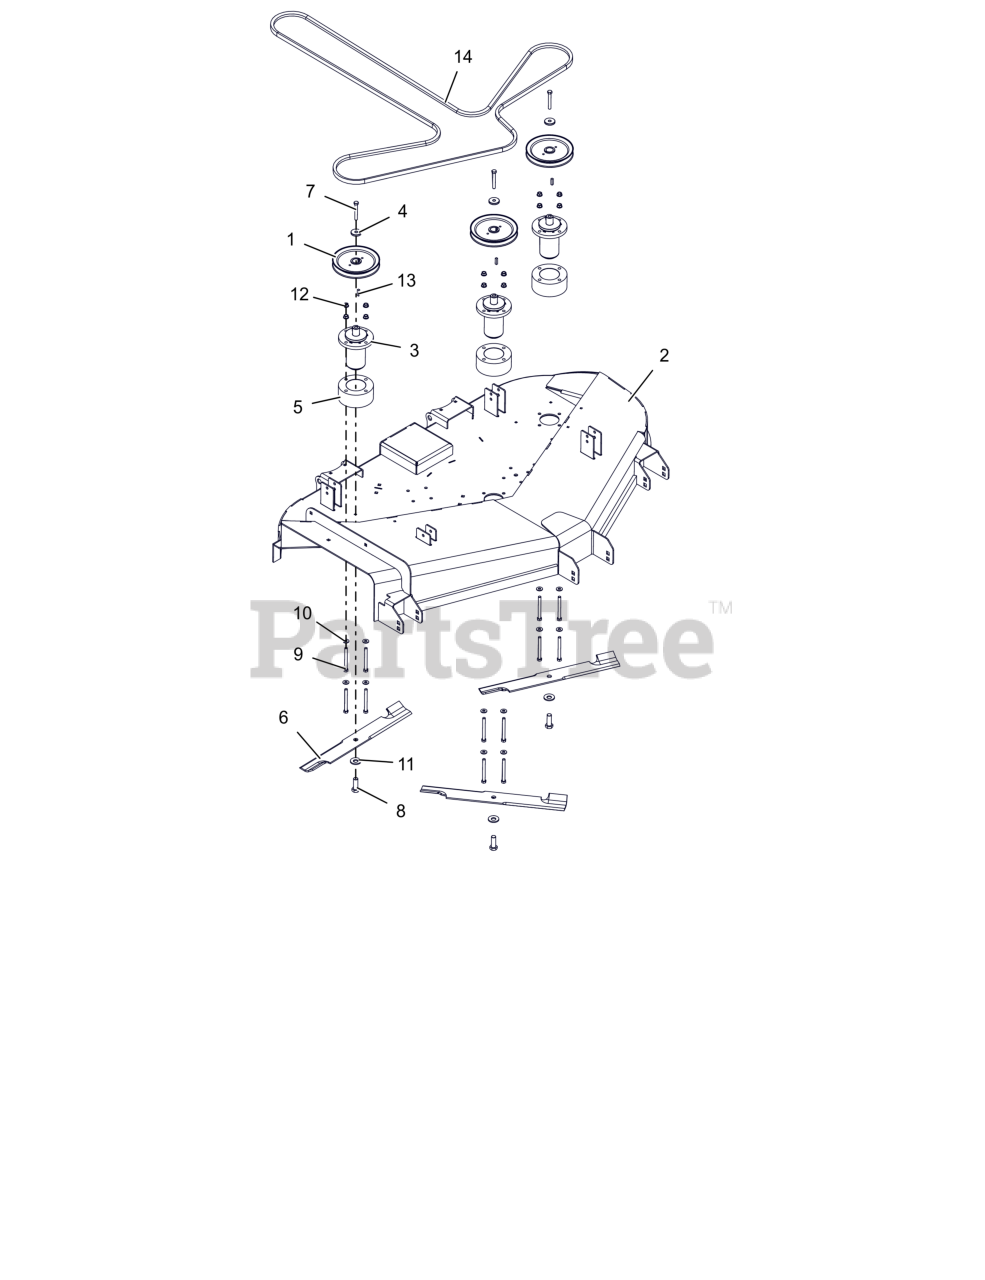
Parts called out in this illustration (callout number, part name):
1	PULLEY, V-1" ID X 6.75" OD
2	WLDMT- PT300/500 TUNNEL DECK
3	ASM, MAINT FREE ALUM SPINDLE
4	RETAINER, SHEAVE
5	SPCR, SPINDLE
6	BLADE, MOWER 20.940 X 1.00 LIFT
7	BLT, HEX .38-16X2.75 G8 ZCC
8	BLT, HEX .62-18X1.75 G8 ZCC
9	BLT, HEX 0.375-16X3.75 GR8 ZCC
10	WSHR,FLT .375X.875X.083 ZCC
11	WSHR-BLVL .669X1.535X.138
12	NUT-LK-CTR-FLG .375-16 GF ZCC
13	KEY, SQ .25X.25X1.00 RC 40-50
14	V-BELT, HB SECTION
